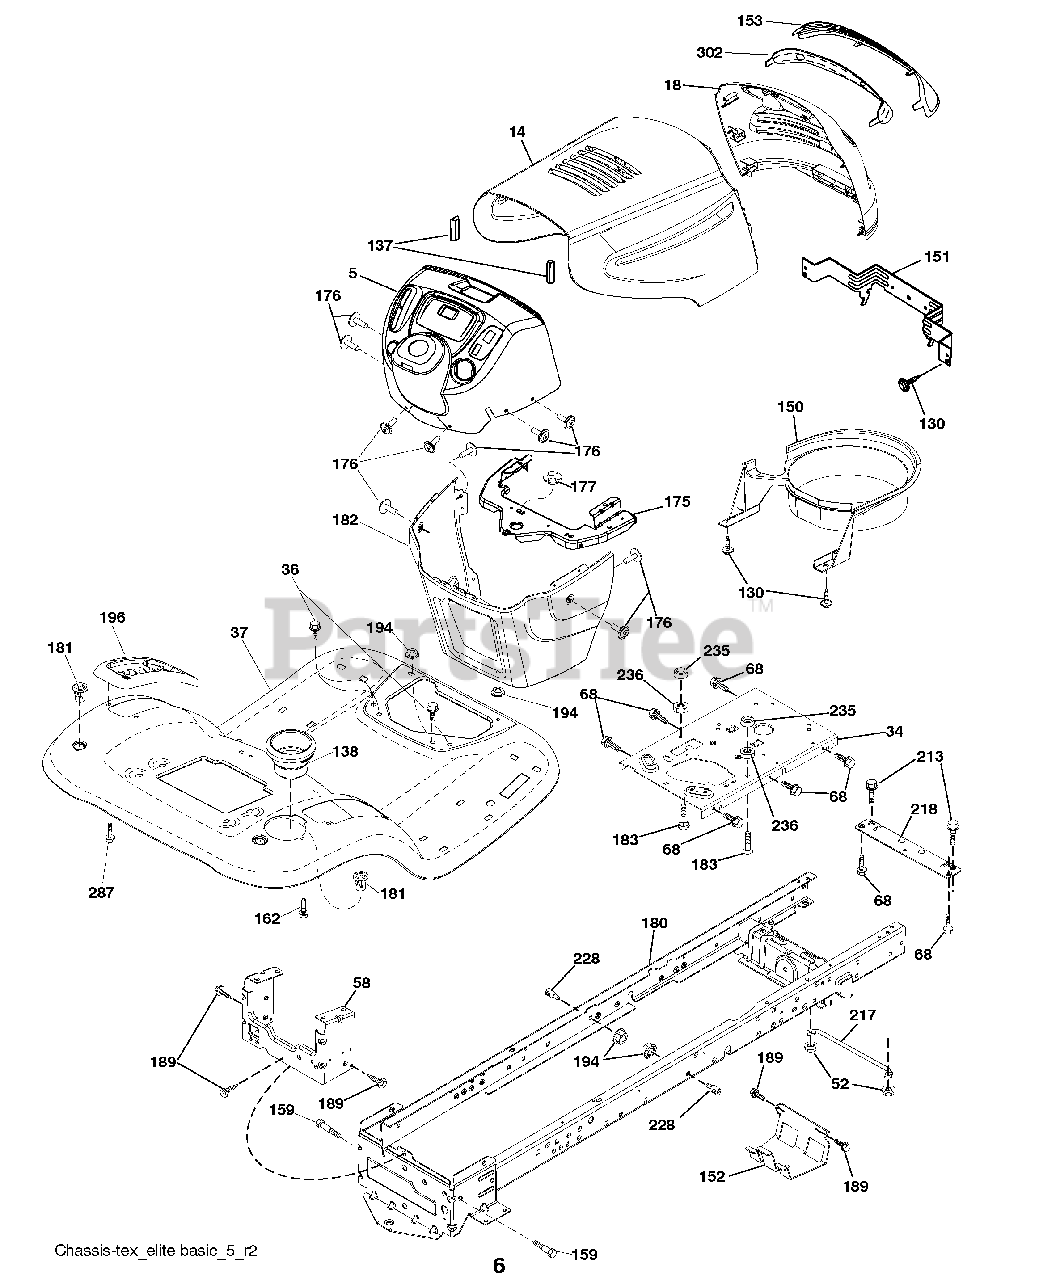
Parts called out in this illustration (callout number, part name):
5	Dash
18	Grille
34	Plate Engine
36	Screw 5/16-18 x 3/4
52	Nut Lock 5/16-18
58	Drawbar Upper
68	Screw Thdrol 5/16-18 x 1/2
130	Screw #10 x 0.750
137	Bumper Hood
138	Cupholder
150	Duct Heat Hood
151	Bracket Pivot
152	Shield Browning
153	Lens Grille
159	Screw Hexwsh Thdrol 3/8-16 x 3/4
162	Screw Hex Wsh Hi-Lo 1/4 x 1/2
175	Crossmember
176	Screw 10-24 x 5/8 Wshd Qdrx
177	Bushing Steering
180	Chassis
181	Bushing Mtg. Fender Crgo.
182	Dash Lower
183	Bolt 5/16-18 x 1-1/4
189	Screw 5/16-18 x 3/4
194	Nut Lock Hex Flange 5/16-18
196	Console Asm. Deck Lift
213	Bolt 5/16-18 x 3/4
217	Rod Pivot Hood
218	X-Piece Hood Step
228	Stud Fastener
235	Spacer Fender
236	Nut Center Lock 5/16-18
287	Screw 1/4-20 x 3/8
302	Insert Lens Reflective
